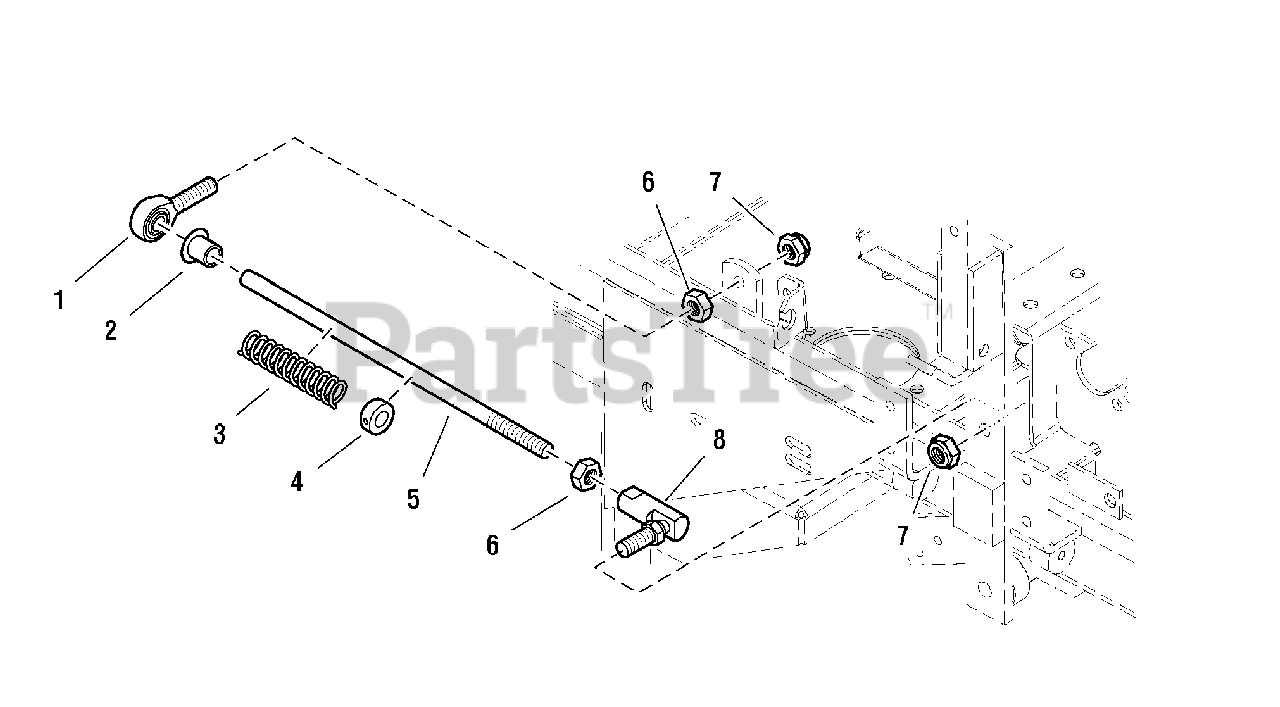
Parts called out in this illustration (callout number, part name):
1	BALL JOINT, 3/8-24 Male
3	SPRING, Compression
4	COLLAR, 3/8" Set
5	NEUTRAL CONTROL ROD
6	NUT, 3/8-24 Hex
7	NUT, 3/8-24 Hex Nylon Lock
8	BALL JOINT, 3/8" Female Studded
